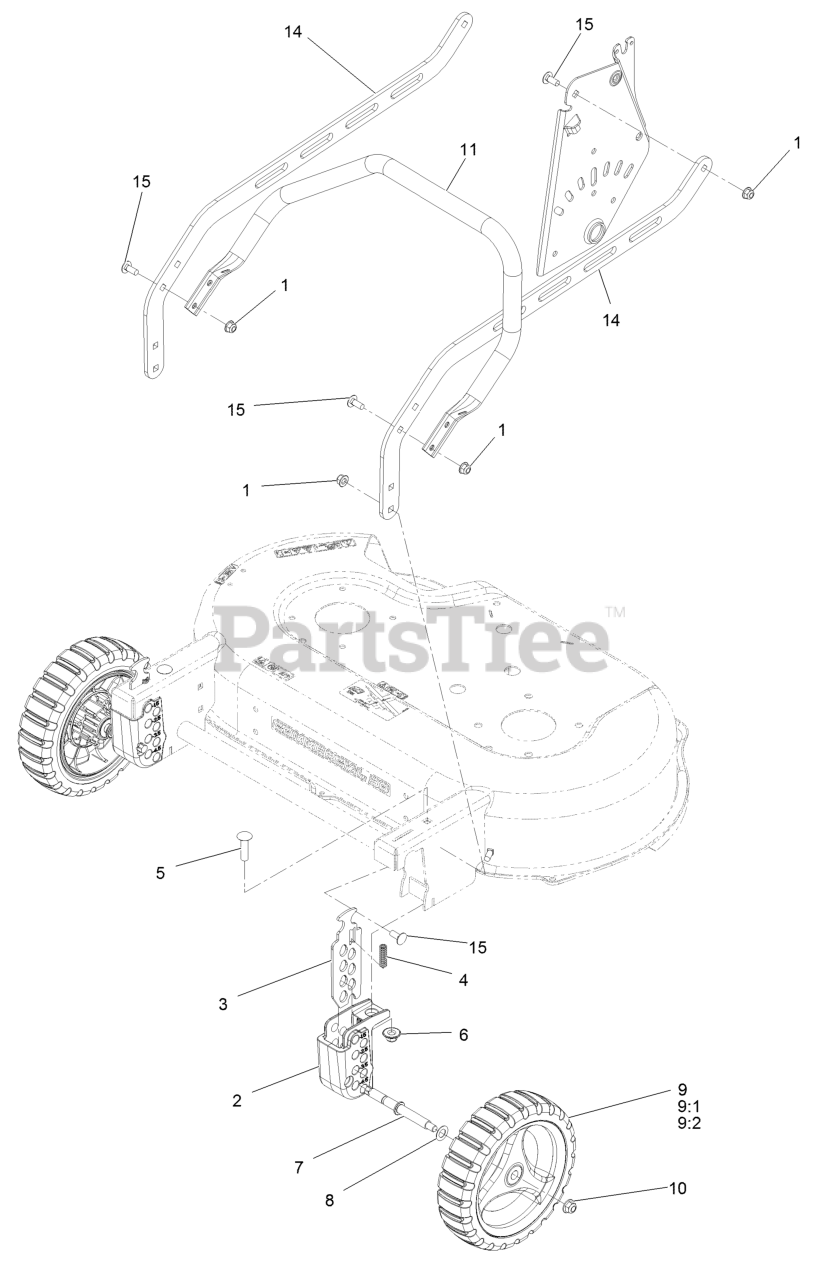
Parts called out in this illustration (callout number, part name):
1	Nut-Nyloc 5/16-18 Flg
2	Block-Front Quadrant
3	Plate, Front Height
4	Spring-Compression
5	Bolt-Carriage 3/8-16 X 1 1/2
6	Nut-Nyloc 3/8-16 Flg
7	Axle-Wheel
9	Wheel ASM, 9" W/Bearings
9:1	Wheel ASM, 9"
9:2	Bearing-Ball
10	Nut-Nyloc 3/8-16 Flg
11	Guard-Engine
15	Bolt-Carriage 5/16-18 X 3/4 Short Neck
